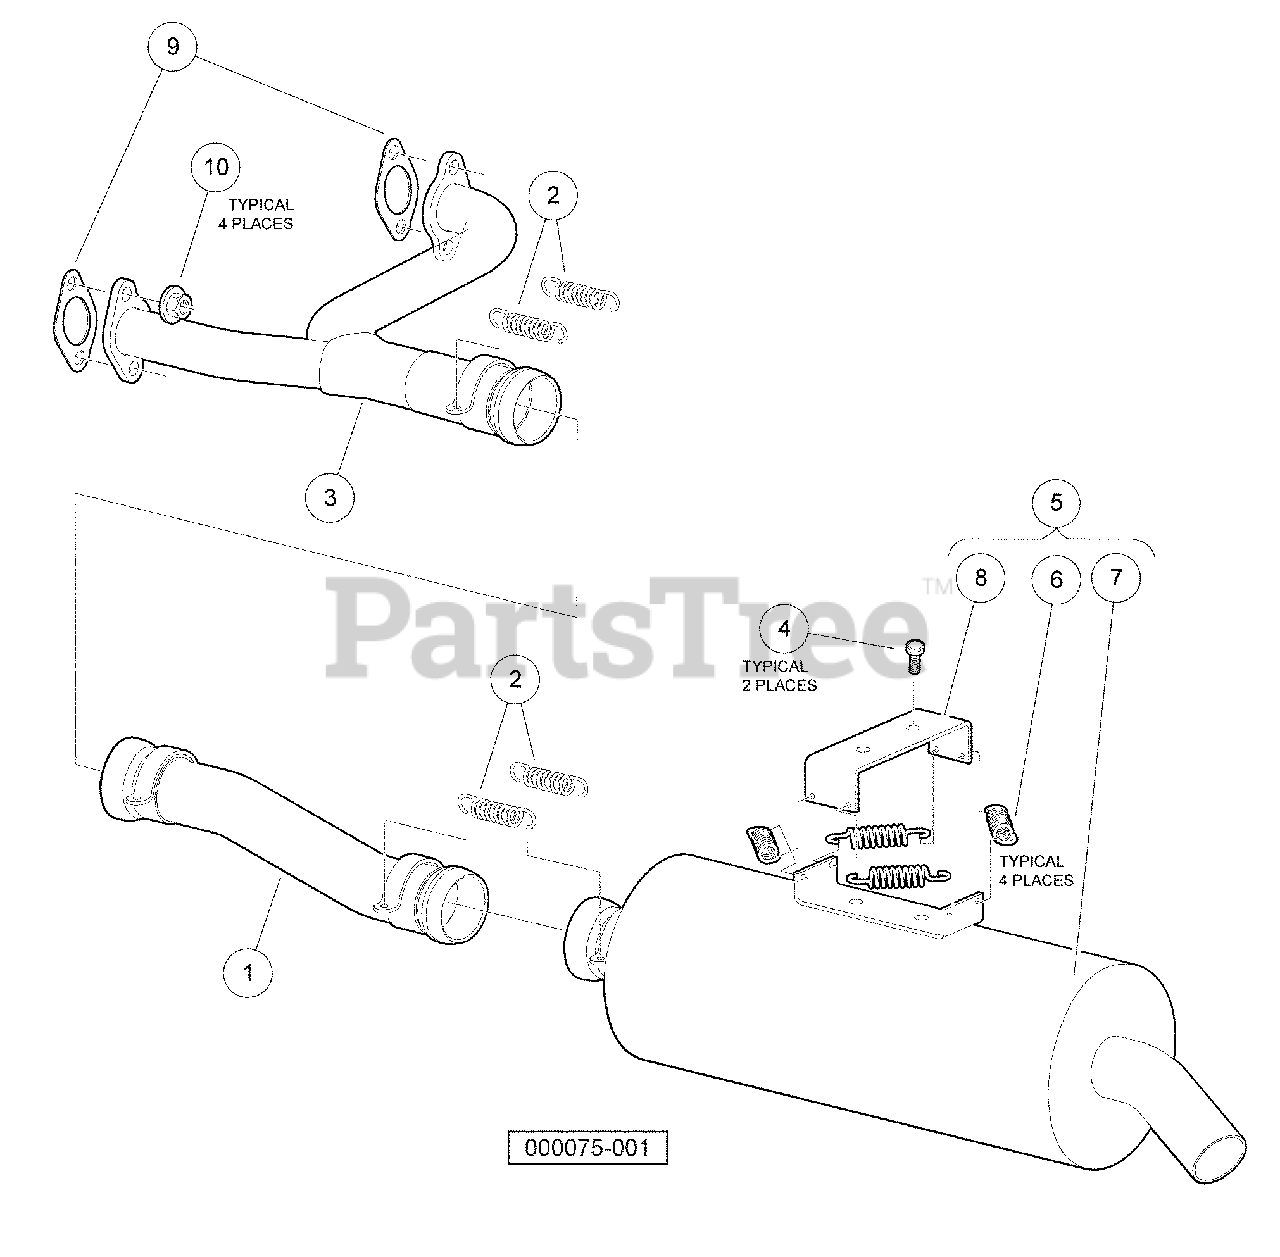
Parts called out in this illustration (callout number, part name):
1	Pipe, Exhaust Intermediate
2	Spring, Exhaust
3	Header, Exhaust, Gas
4	Bolt Flanged Head, M8 X1.25x 16 with Loctite
5	Asm, Muffler, AWD Homologation
6	Spring, Exhaust
7	Muffler
8	Bracket, Muffler
9	Gasket, Exhaust, Gx620
10	Nut Flg, M8 X 1.25 Serrated
